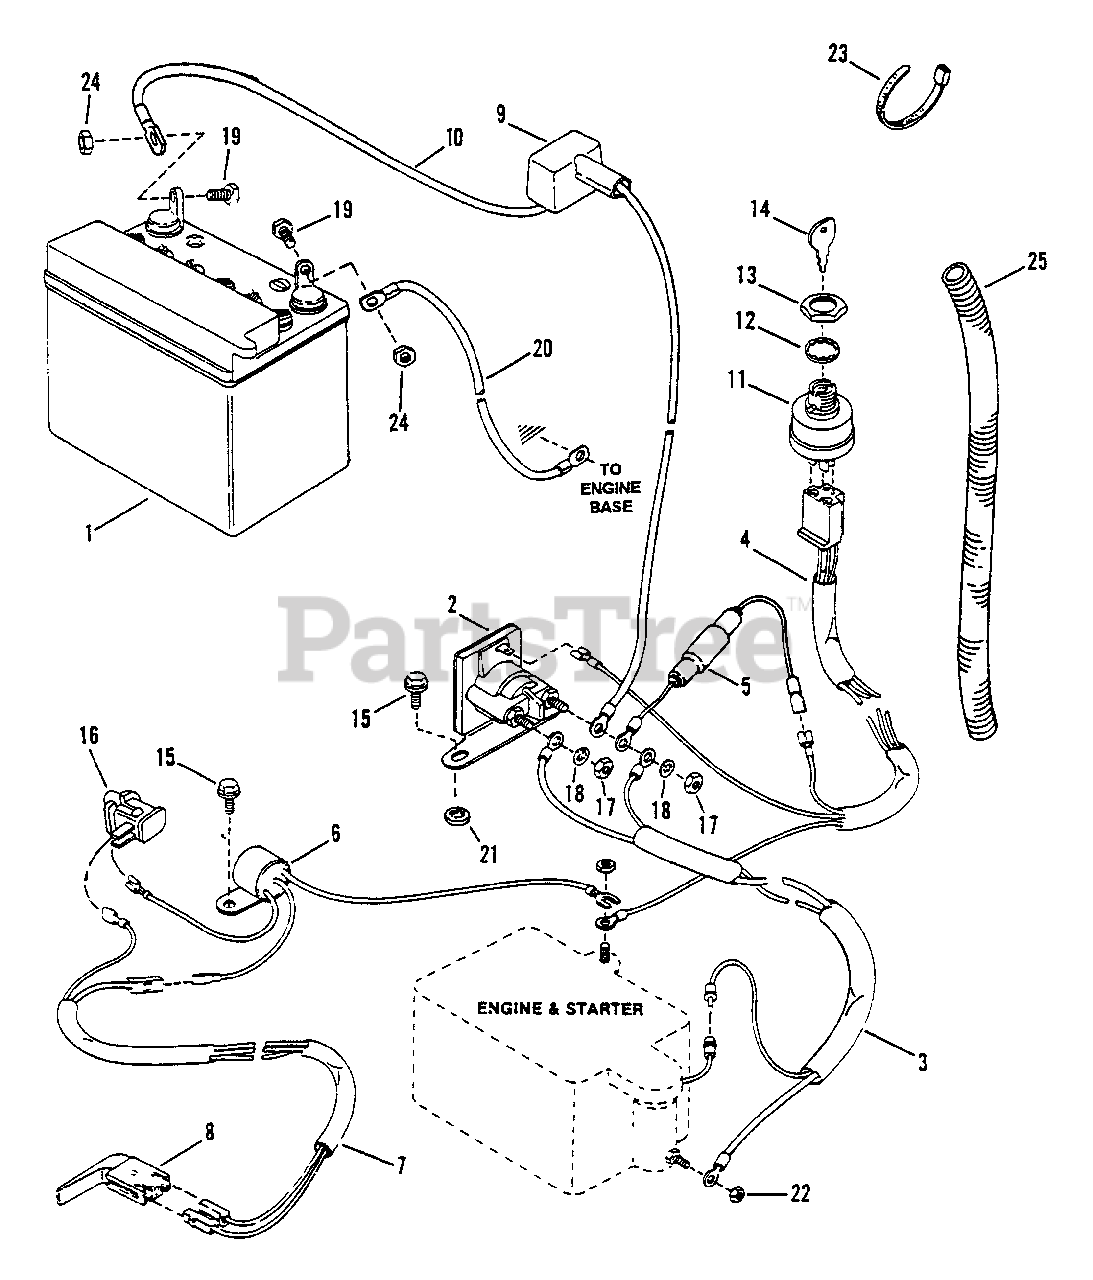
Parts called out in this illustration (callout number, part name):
1	KIT, 12V Dry Charge Battery
2	SOLENOID
3	HARNESS, Starter Wiring (Briggs)
4	HARNESS, Ignition Wiring (Briggs)
5	HOLDER, Fuse
6	INTERLOCK (Briggs)
7	HARNESS, Deck Interlock Wiring
8	SWITCH, Deck Interlock
9	COVER, Battery Cable
10	CABLE, Positive (Red)
11	SWITCH, Ignition
12	WASHER,5/8 Internal Tooth Lock
13	NUT, 5/8-32 Hex
14	KEY, Switch (With Cover)
15	SCREW, 1/4-20 x 1/2" Self-Tapping
16	SWITCH, Seat
17	NUT, 1/4-20 Hex
18	WASHER, 1/4 Internal Tooth Lock
19	SCREW, 1/4-20 x 5/8" Hex Head Cap
20	CABLE, Negative
21	RETAINER, 1/4 Bolt
22	NUT, 1/4-20 Hex
23	TIE, 7" Long Cable
24	NUT, 1/4-20 Hex Lock
25	CONDUIT
